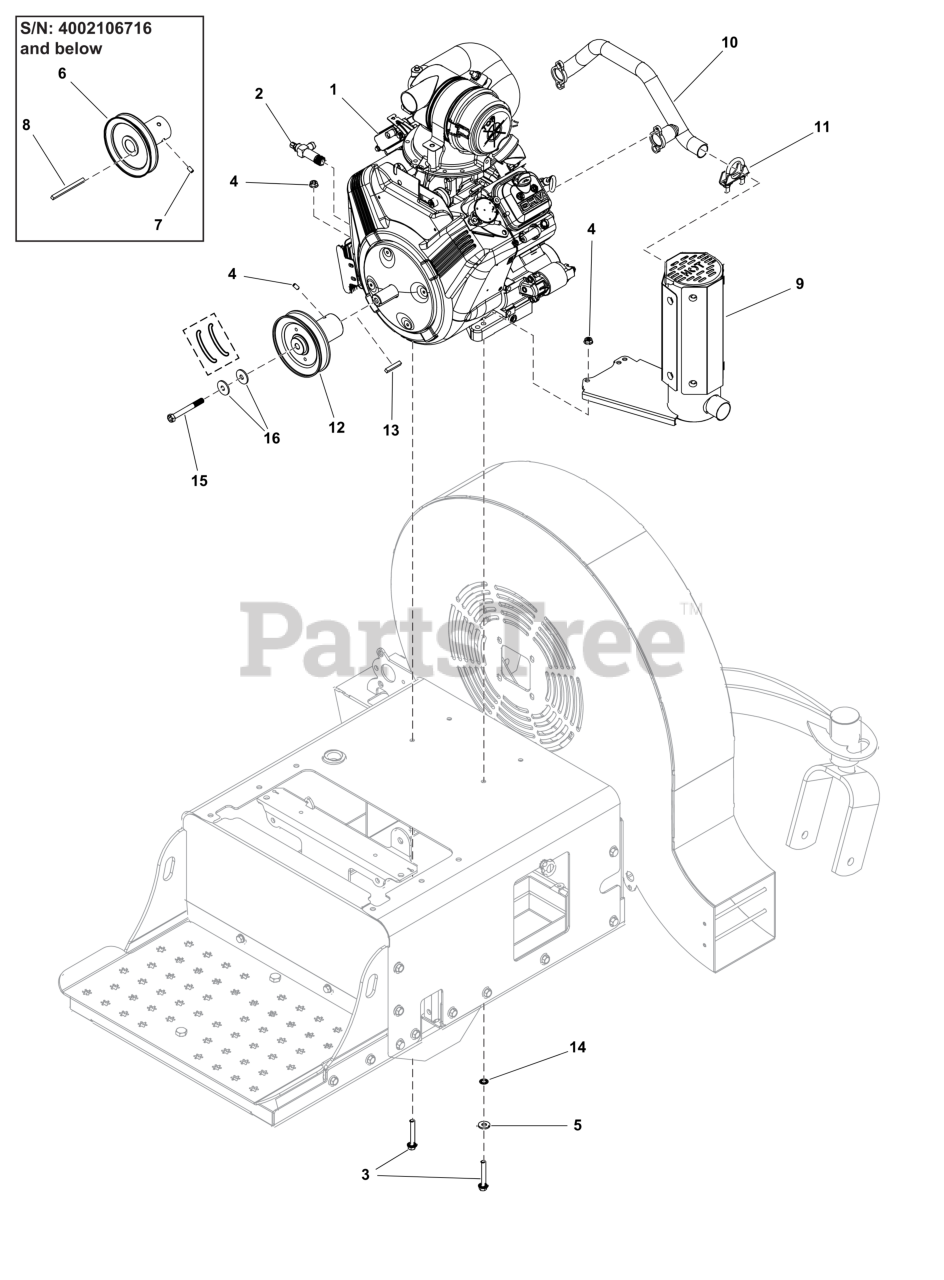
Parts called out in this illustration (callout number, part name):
2	VALVE, OIL DRAIN SHUT OFF
4	NUT, 5/16-18 HEX SERR
6	KIT, DRIVE PULLEY, FB2000/X3000
7	SET SCREW
8	KEY
10	MANIFOLD
11	CLAMP, MUFFLER
12	PULLEY, STUB SHAFT
13	KEY 1/4 SQ X 1 1/2
14	WASHER, 5/16" INT. TO
15	BOLT, 3/8-24 X 3-1/4, GD8 PHOS
16	WASHER, Beveled
